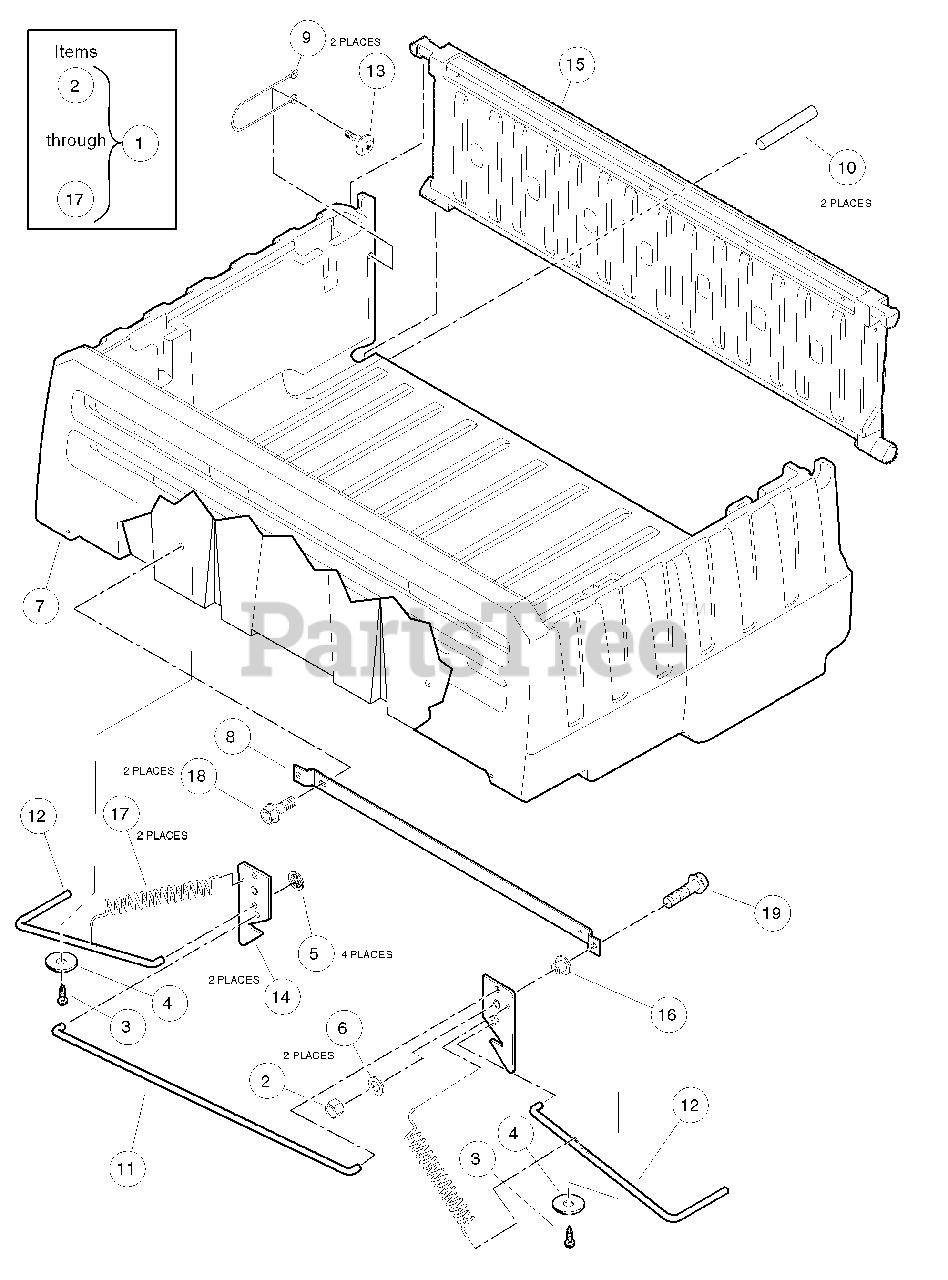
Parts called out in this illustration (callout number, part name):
1	Assembly, Bed
2	Locknut, 3/8-16 Dimpled
3	Screw, Hex Washer Head 1/4-14 X .75
4	Washer, 5/16 Type B Flat
5	Pushnut, 3/8
6	Washer, 3/8 Flat Type A
8	Support, Latch Link
9	Lanyard, Tailgate
10	Pin, Support
11	Rod, Long Link
12	Rod, Bed Lift, Short Bent
13	Bolt Lanyard
14	Catch, Tilt Bed
15	Tailgate, Husqvarna
16	Bearing, Bronze, 1/2x9/32
17	Spring, Tilt Latch 3.4 Lb/in
18	Screw, 1/4-20 X 1.0 Hex-Head Cap
19	Screw, 3/8-16 X 1.00 Hex-Head Cap
